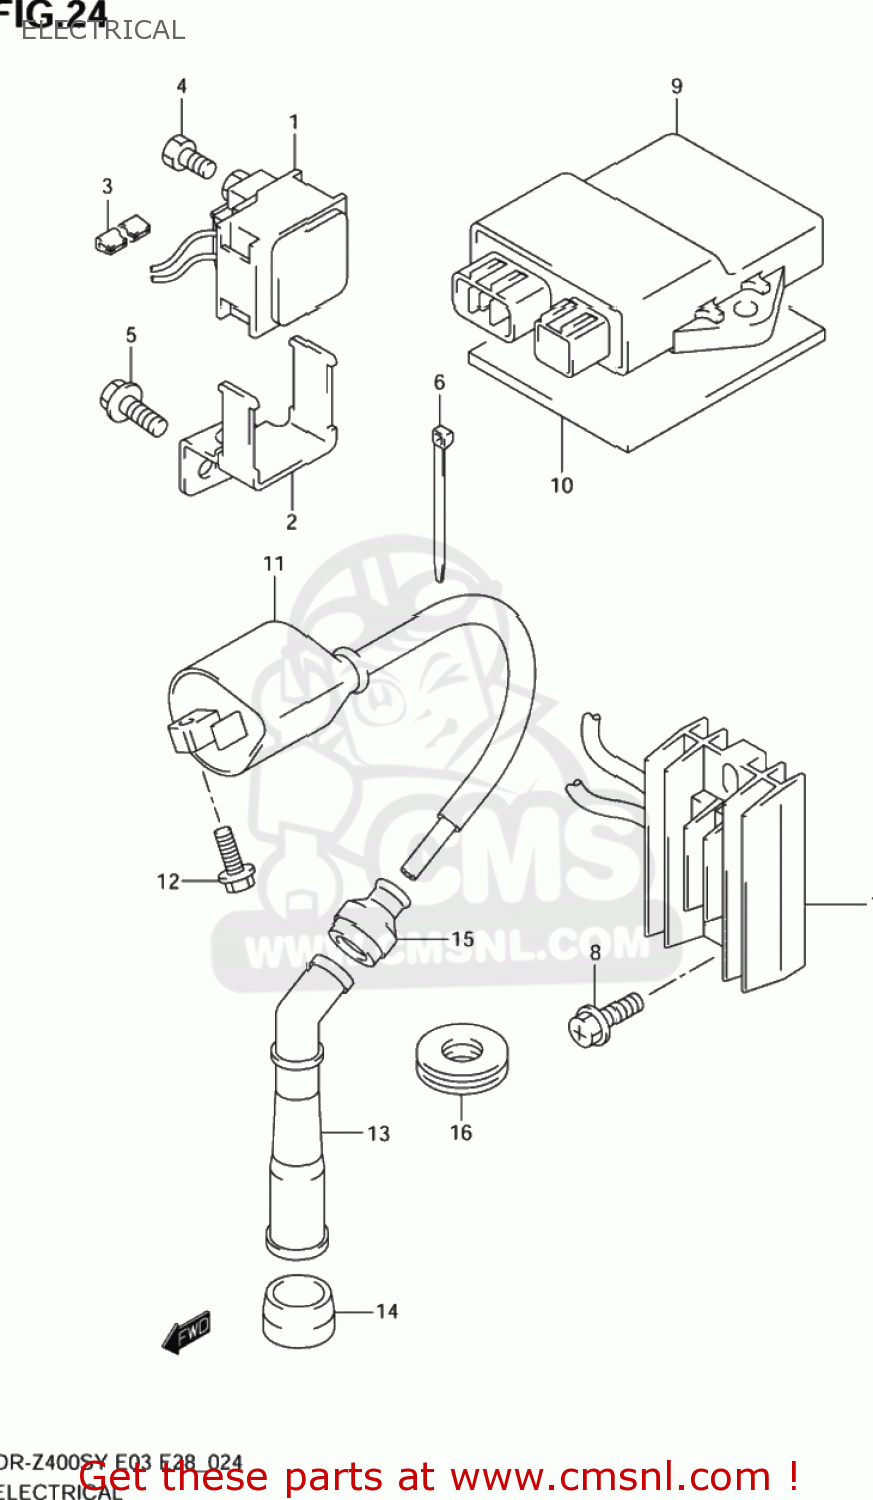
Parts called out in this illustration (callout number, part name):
1	RELAY ASSY,STARTING MOTOR
2	BRACKET,STARTING MOTOR RELAY
3	PROTECTOR,STARTING MOTOR LEAD
4	SCREW(6X8)
5	BOLT
6	CLAMP(L:145)
7	RECTIFIER ASSY
8	BOLT
9	CDI UNIT
10	PROTECTOR(170X95X3.0)
11	COIL ASSY,IGNITION
12	BOLT
13	CAP,SPARK PLUG
14	SEAL,SPARK PLUG CAP
15	SEAL,HIGH TENSION CORD
16	COVER,SPARK PLUG CAP
